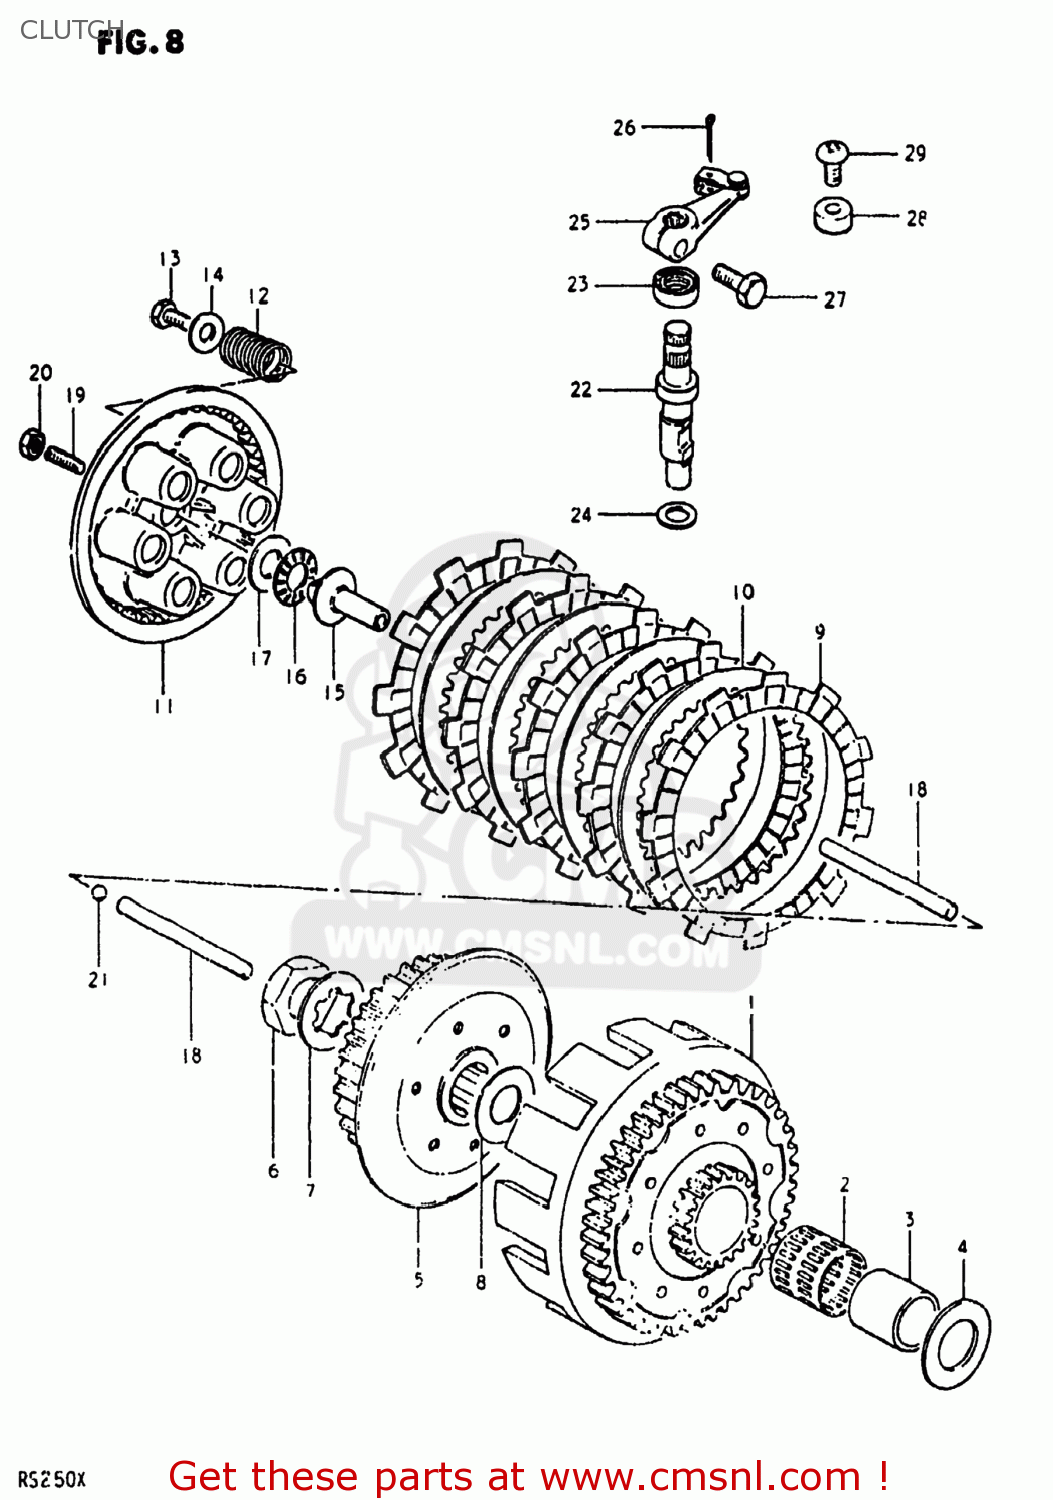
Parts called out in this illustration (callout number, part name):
1	GEAR ASSEMBLY,PRIMARY DRIVE
2	ROLLER BEARING (25X30X2
3	SPACER
4	WASHER(20X38X2)
5	HUB,CLUTCH SLEEVE
6	NUT (20MM)
7	WASHER,LOCK
8	WASHER(20X38X2)
9	PLATE,CLUTCH DRIVE (MCA)
10	PLATE,CLUTCH DRIVEN (NAS)
11	DISC,CLUTCH PRESSURE
12	SPRING
13	BOLT, UPPER
14	WASHER
15	PIECE,CLUTCH PUSH
16	BEARING(15X28X2)
17	WASHER
18	ROD,CLUTCH PUSH
19	SCREW
20	NUT 6MM
21	BALL
22	SHAFT,CLUTCH RELEASE C
23	OIL SEAL
24	WASHER (14.2X22X1)
25	ARM,CLUTCH RELEASE
26	PIN
27	BOLT
28	GUIDE,CLUTCH CABLE
29	SCREW
